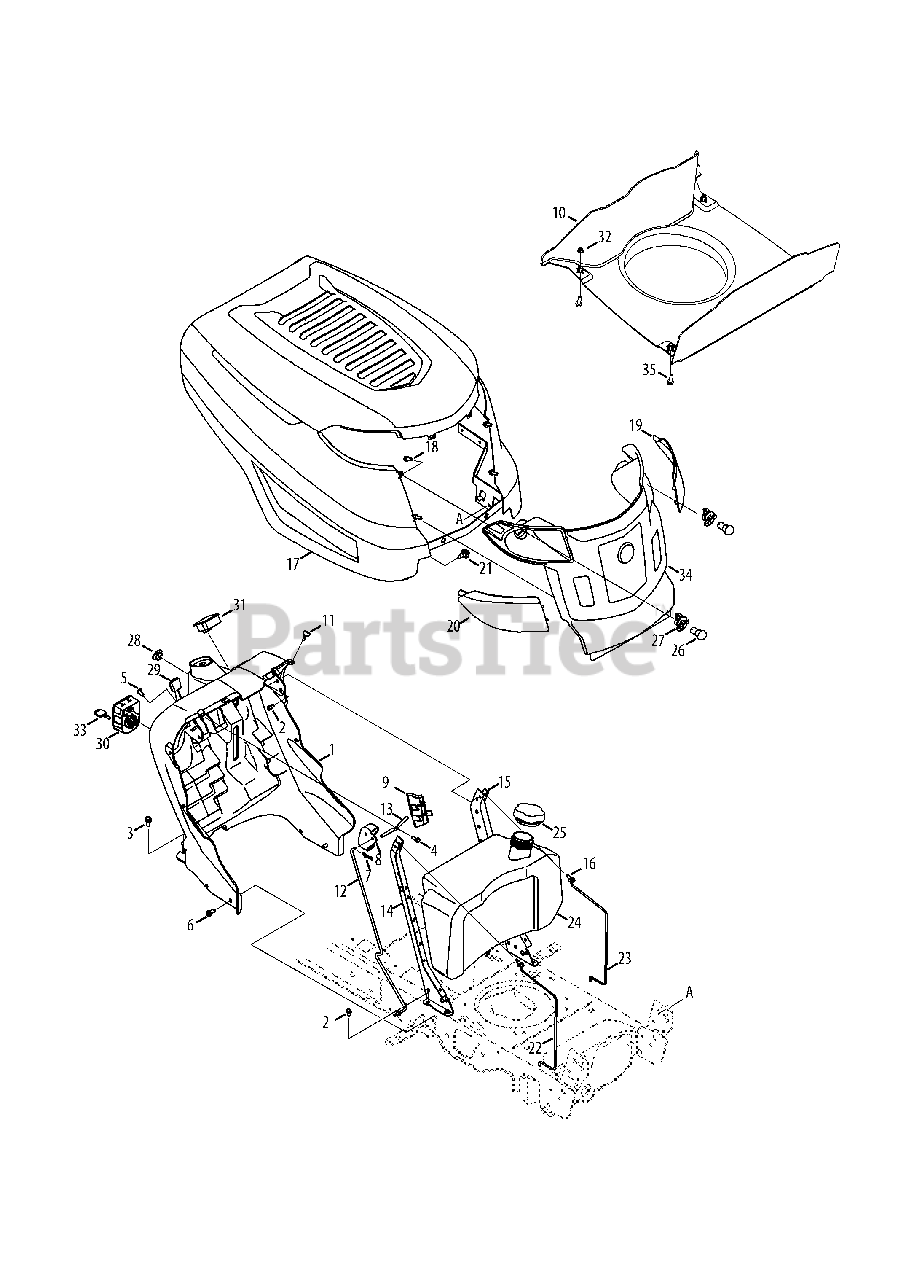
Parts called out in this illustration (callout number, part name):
1	Dash Assenbly
2	Taptite Screw ,1/4-20:0.500
3	Taptite Screw ,5/16-18:.750
4	Hi-Lo Screw, 1/4-15:0.750
5	Screw, 1/4-14:0.625
6	Taptite Screw ,5/16-18:0.750
7	Bow Tie Cotter Pin
8	Dash Lever
9	Cruise Cover
12	Control Rod
14	RH Support Plate
15	LH Support Plate
16	Tap Screw, 1/4-20, 0.625
18	Screw, 1/4 DIA:.750
21	Shoulder Screw, .43 x .29
22	LH Tank Support Rod
23	RH Tank Support Rod
26	Headlight Assembly - LED
26	Headlight Assembly Kit - LED
27	Lamp Socket
28	Choke Plug
29	Throttle/Choke Cable, 25"
30	Key Switch Module
31	Hour Meter
32	Flangelock Nut, 1/4-20
33	Key, Assembly
35	Hex Screw, 1/4-20:.620
